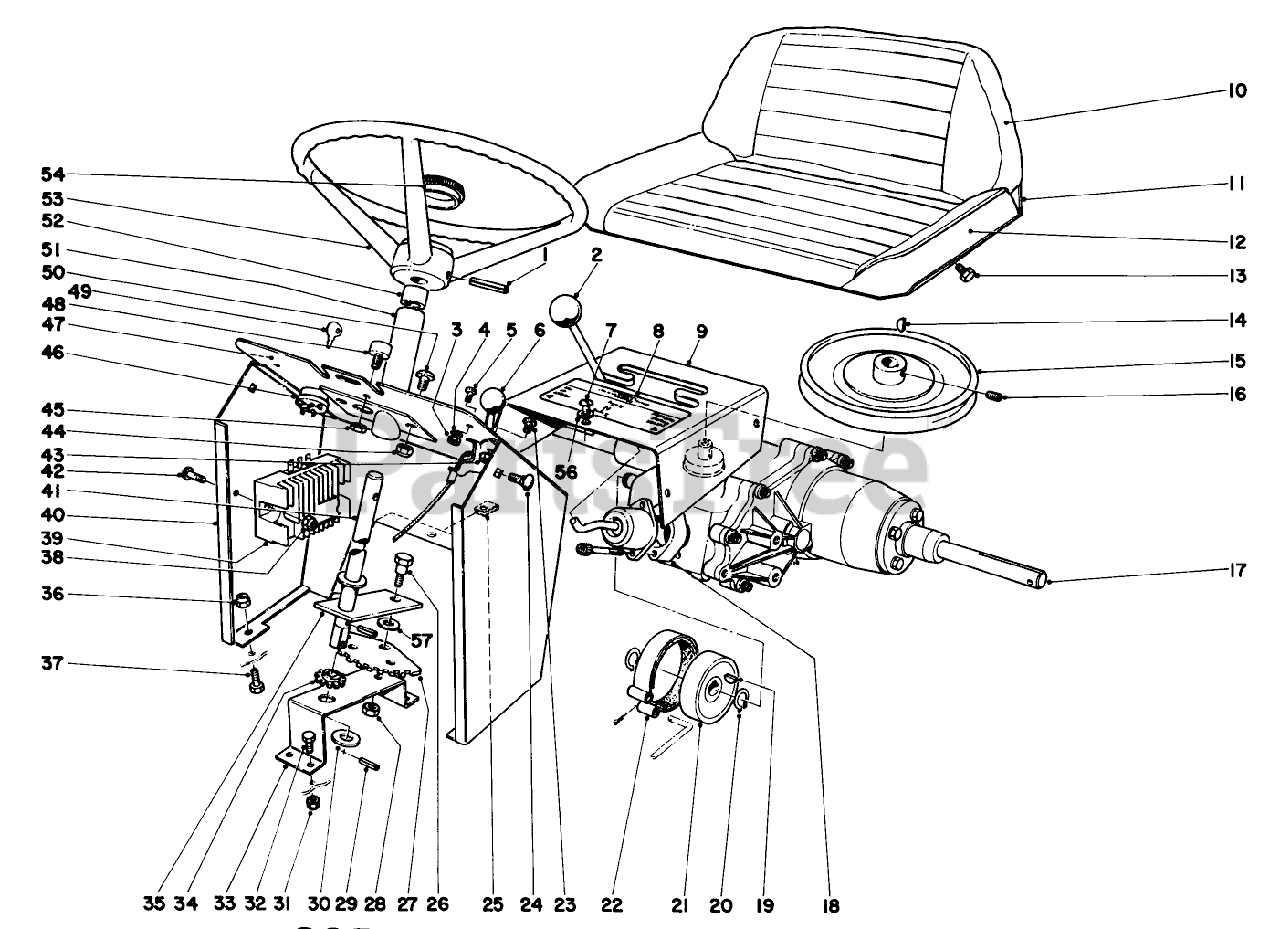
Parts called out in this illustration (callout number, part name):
1	Roll Pin
3	NUT-HEX
4	WASHER-LOCK, EXT
5	10-24 X 3/8 PAN HD SC
6	Throttle Control
7	SCREW
8	Decal Shift Pattern
9	Tunnel
10	Cushion Back
11	Frame Seat
12	Cushion Seat
13	Screw
14	KEY-WOODRUFF
15	Pulley
16	Set Screw
17	Transaxle
18	Extension Shift Housing
19	KEY-WOODRUFF
20	RING-SNAP, EXTERNAL
21	Brake Drum
22	Brake Band
23	Machine Screw
24	BOLT-CARR
25	SPEED NUT
26	Shoulder Bolt
27	Gear Steering
28	Nut
29	Roll Pin
30	WASHER
31	Nut
32	SCREW-HH
33	Bracket
34	STEERING PINION
35	Retainer Steering Gear
36	Nut
37	SCREW-HH
40	Dash Hood Support 935
41	Steering Shaft
42	Screw, Phillips
43	NUT-KEPS
44	Nut
46	Switch Ignition 935E
47	Decal Dash Panel 935
49	Key
50	Truss Head Screw
51	Steering Tube
52	Bushing
53	Steering Wheel
54	Steering Wheel Cap
56	WASHER-LOCK
57	WASHER
